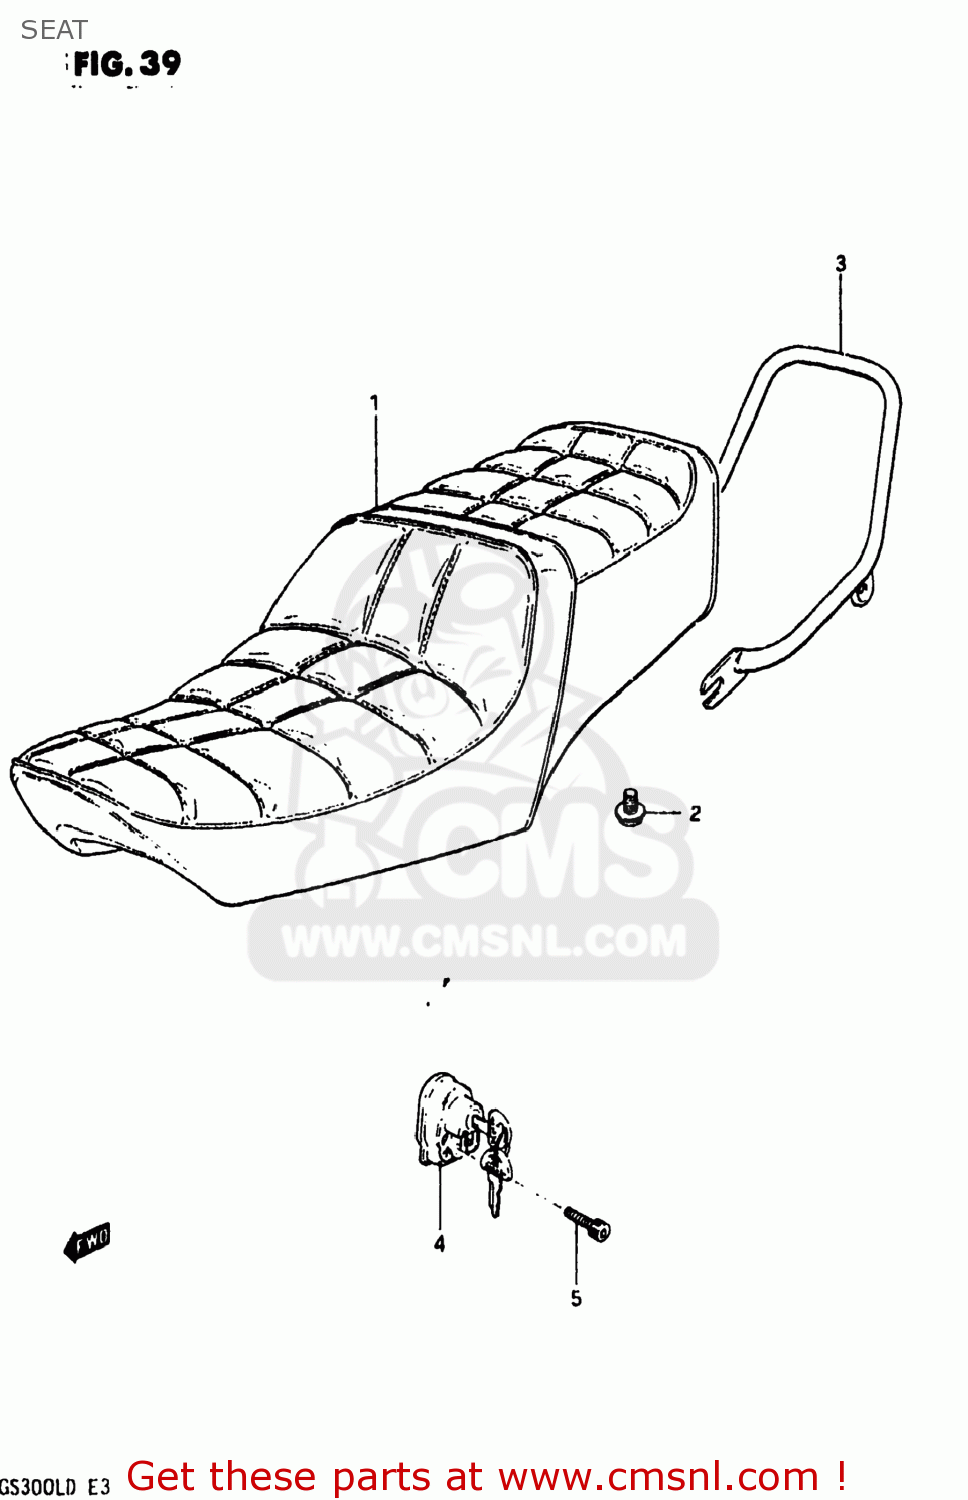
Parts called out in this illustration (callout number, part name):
1	SEAT ASSEMBLY
2	BOLT
3	HANDLE,PILLION RIDER
4	LOCK ASSY,HELMET
5	BOLT 5X25
